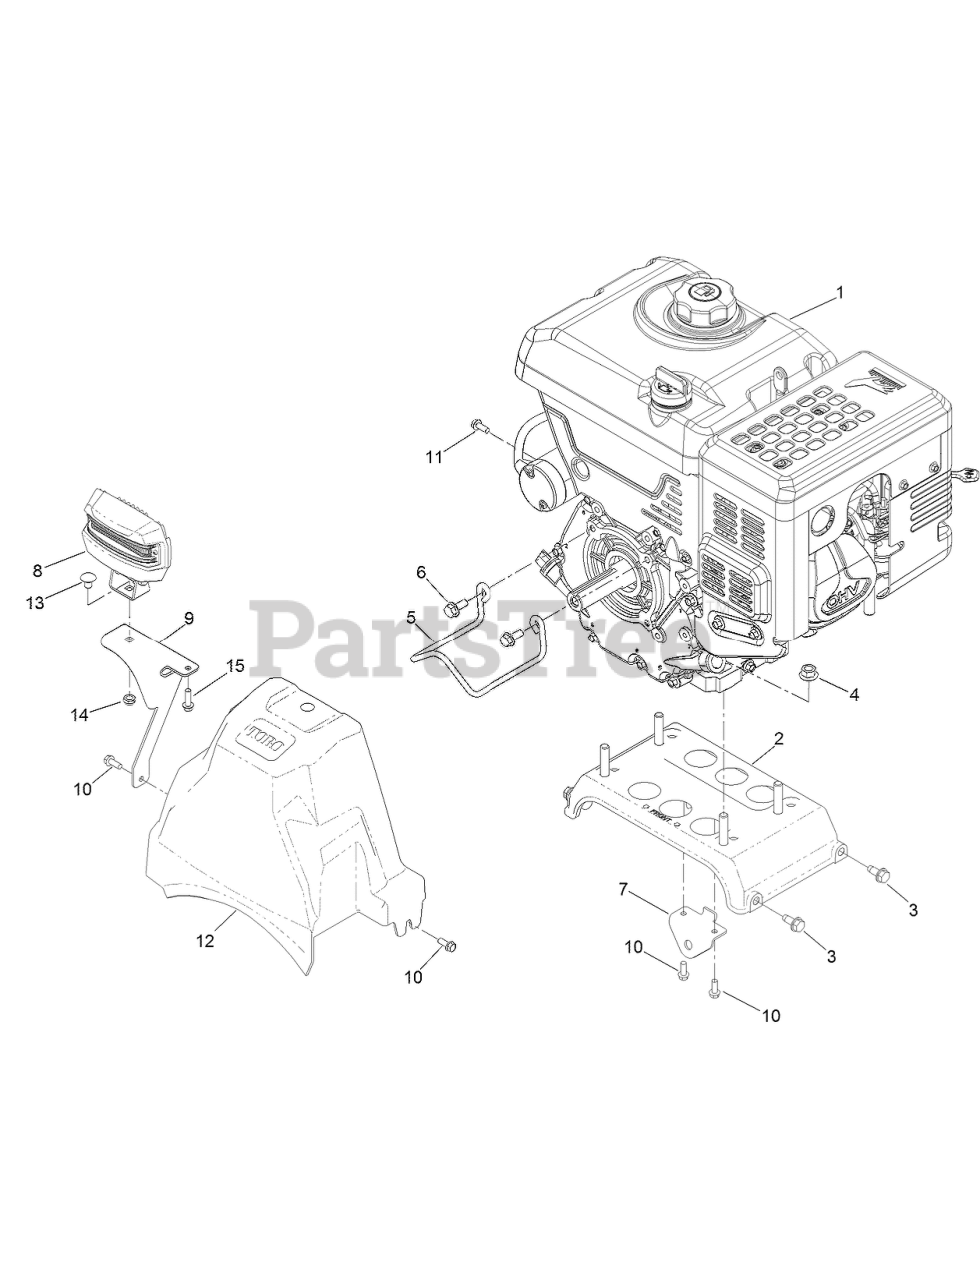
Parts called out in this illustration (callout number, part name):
1	ENGINE-LC175FDS-1
2	ENGINE PLATE ASM
3	SCREW-HWHTF
4	NUT-LOCK
5	GUIDE-BELT
6	SCREW-HH
7	BRACKET-CONTROL, TRACTION
8	LED LIGHT ASM
9	BRACKET-LIGHT
10	SCREW-HWH
11	SCREW-HH
12	COVER-BELT
13	BOLT-CARR
14	NUT-HEX
15	SCREW-PLASTITE, HWH
